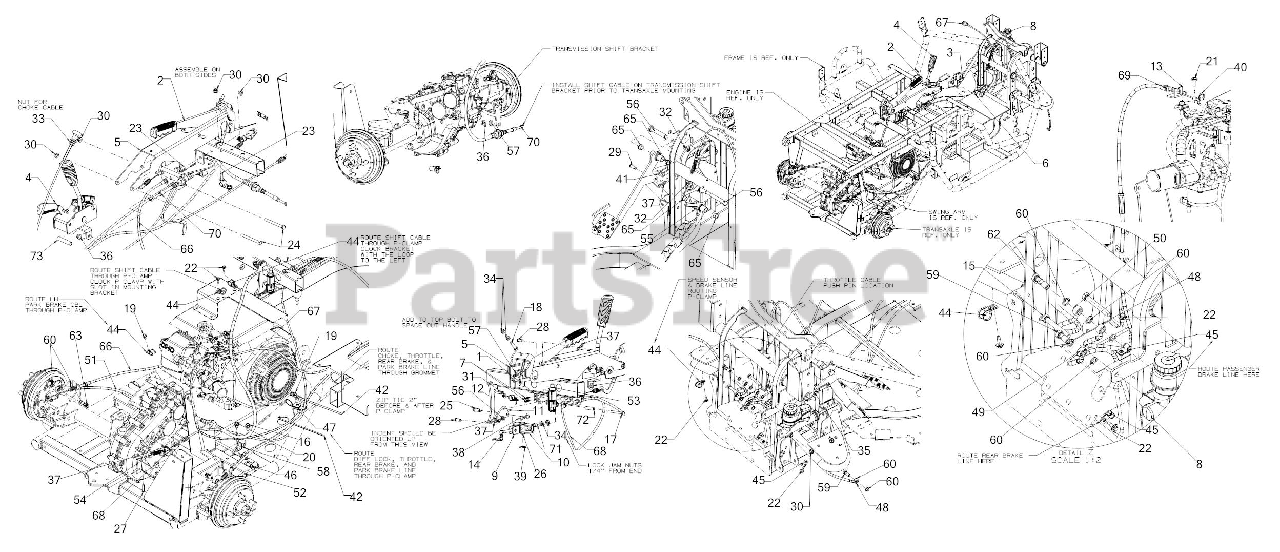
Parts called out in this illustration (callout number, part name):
1	PLATE-SWITCH
2	BRAKE LEVER ASSEMBLY
3	BRAKE PEDAL ASSEMBLY
4	COMPLETE SHIFT DIFF ASSEMBLY
5	PARKING BRAKE CONTROL MOUNT BRACKET
6	GAS PEDAL ASSEMBLY
7	SCREW #10-24X11/16:T25
8	MASTER CYLINDER ASSEMBLY
9	CABLE MOUNTING BRACKET
10	EQUAIZER BRACKET
11	BRAKE LEVER BRACKET
12	BRAKE LINK BRACKET
13	THROTTLE MOUNT BRACKET
14	SCREW 5/16-18 x 2.5 GR 5
15	HEX SCREW 5/16-18 x 2.25 GR5
16	SCREW 5/16-18 x .750
17	SCREW 1/4-20 x 2 GR5
18	SCREW 5/16-18 x 1.25 GR5
19	SCREW 1/4-20 X.500
20	SCREW 5/16-18 x .500
21	SCREW M5-.8X10MM SLOT/TORX
22	SCREW M6-1 x .625
23	SCREW 5/16-18 x .875 GR5
24	SCREW 5/16-18 x 3.25 GR5
25	CLEVIS PIN .375 x .969
26	PIN .625 x 1.37
27	CLEVIS PIN .25 x 1.00
28	CLEVIS PIN 5/16 x 3/4
29	CLEVIS PIN .312 x 1.0
30	FLANGE LOCK NUT 5/16-18
31	FLANGE LOCK NUT
33	HEX FLANGE NUT
35	HEX JAM NUT 5/16-24 GR 5
36	HEX FLANGE NUT M8X
37	BOW TIE COTTER PIN 1/4-5/16
38	PIN:COTTER
40	EXTERNAL RETAINING RING 7MM
41	ADJUSTABLE ROD END
42	7" CABLE TIE
43	14.5" CABLE TIE
45	MOUNTING CLAMP
46	J TYPE CLIP
47	HOSE CLAMP 1.0"
48	FRONT BRAKE HOSE (RH)
49	MASTER CYLINDER BRAKE HOSE (REAR)
50	FRONT BRAKE HOSE (RH)
51	FRONT BRAKE HOSE (LH)
52	BRAKE HOSE (RH)
53	SEALED PLUNGER SWITCH
54	EXTENSION SPRING .420X1.50
55	GAS PEDAL TORSION SPRING
56	FLAT WASHER
57	FLAT WASHER
58	TEE FITTING
59	BANJO FITTING
60	BANJO FITTING
62	BANJO BOLT FITTING
63	BANJO BOLT 3/8-24
64	SHOULDER BOLT
65	NYLINER BEARING
66	BRAKE CONTROL CABLE
67	CONTROL CABLE
68	DIFF LOCK CONTROL CABLE
69	THROTTLE CONTROL CABLE
70	SHIFT CONTROL CABLE
72	SPACER:.260 x .372 x 1.420
